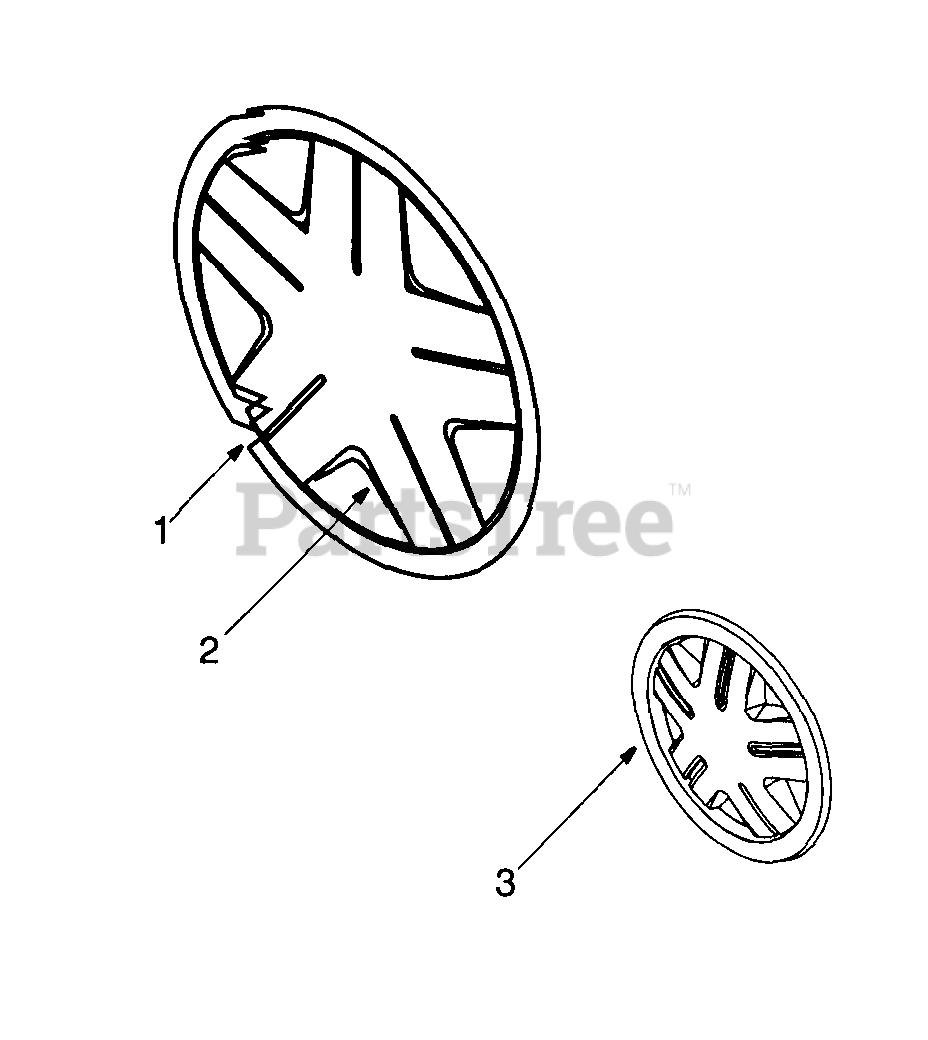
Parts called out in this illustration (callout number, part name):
1	Spring Clip
2	Hubcap: Grey 4"
3	Hubcap: Grey 8"
